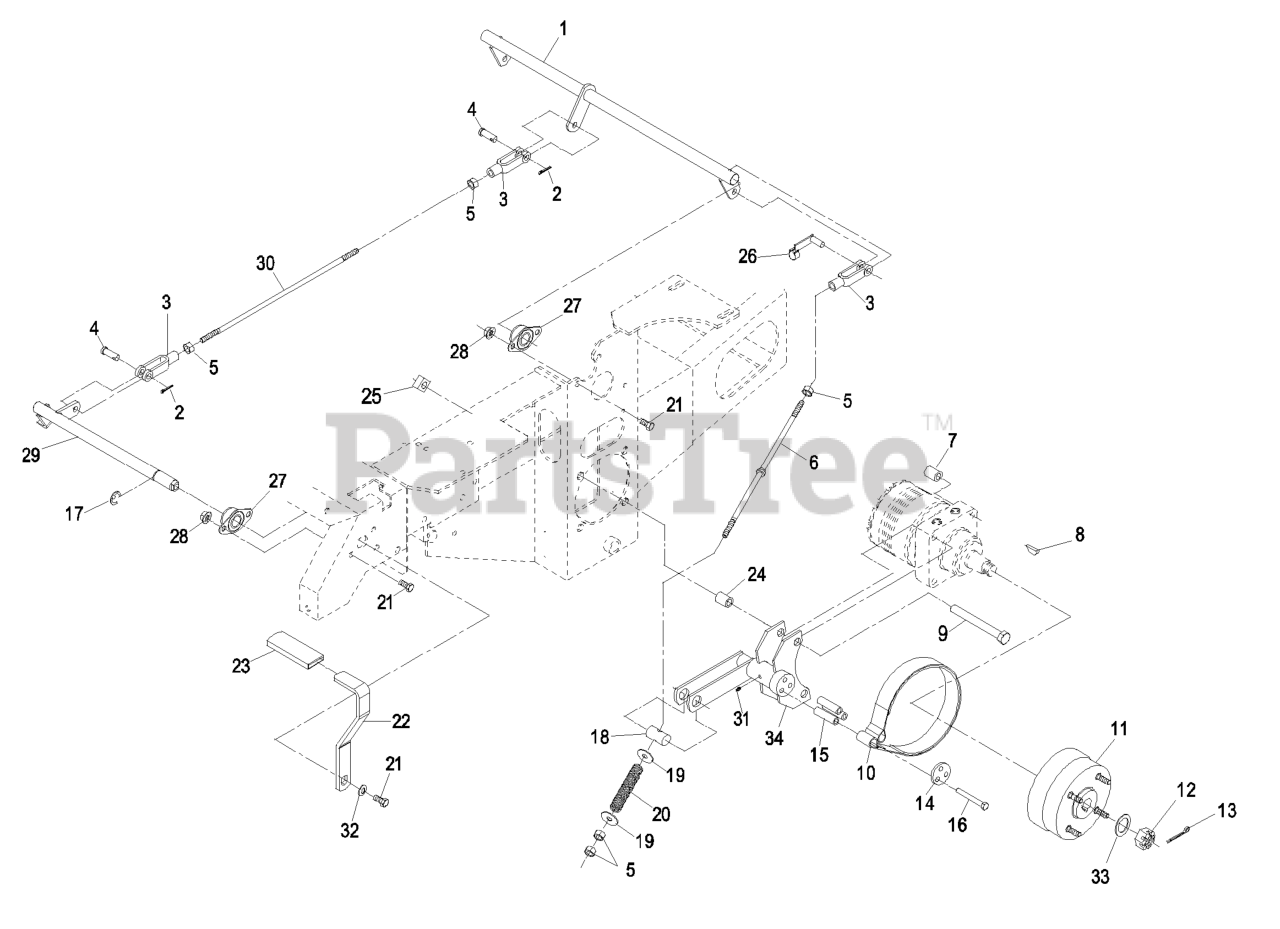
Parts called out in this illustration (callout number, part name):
1	CRANK-BRAKE, PARK
2	PIN-COTTER
3	YOKE-LINKAGE, BRAKE
4	PIN-CLEVIS
5	NUT-HEX
6	ROD-BRAKE
7	SPACER,WHEEL
8	KEY-WOODRUFF
9	SCREW-HH
10	BAND,BRAKE
11	WHEEL HUB ASM
13	PIN-COTTER
14	RETAINER-BAND, BRAKE
16	SCREW-HH
18	PIN-TRUNION
19	WASHER-FLAT
20	SPRING-BRAKE
21	SCREW-HH
22	ASM,BRAKE HANDLE W/ GRIP
23	GRIP-LEVER
24	SPACER,WHEEL
25	NUT-SQUARE, SPECIAL
26	PIN-SPRING, CLEVIS
27	BEARING-FLANGE, SIDE
28	NUT-HHF, WHIZ
29	SHAFT-BRAKE, PARKING
30	LINKAGE-HANDLE, BRAKE
31	FITTING-GREASE
32	WASHER-BELLEVILLE
33	WASHER-SPACER
34	WLD,BRAKE 52
